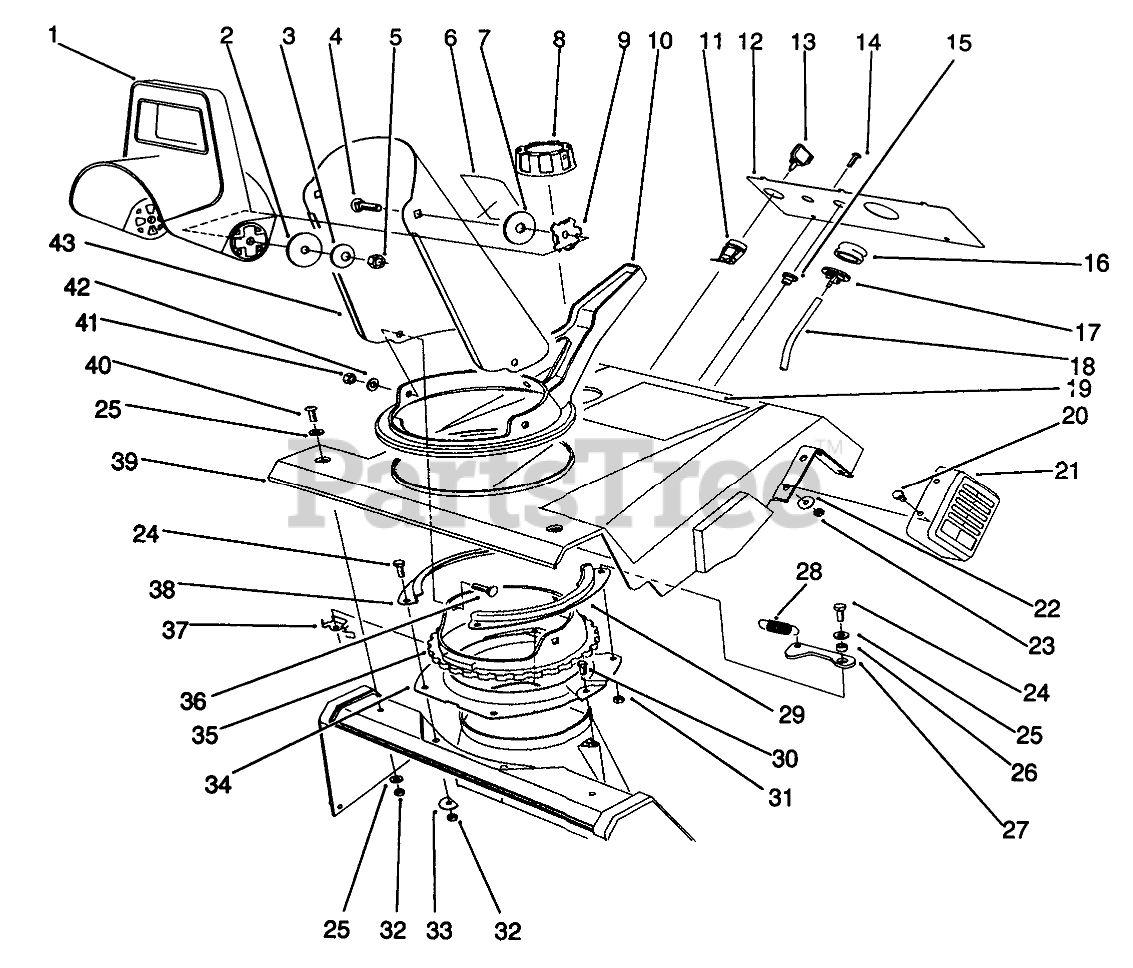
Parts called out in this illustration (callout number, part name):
1	CHUTE-DEFLECTOR
2	WASHER-FLAT
3	WASHER-BELLEVILLE
4	SCREW-CARR
5	NUT-LOCK, NI
6	DECAL-DANGER DISCH.
7	WASHER-RUBBER
8	GAS CAP ASSEMBLY
9	PLATE-FRICTION
10	CHUTE - HANDLE
11	SWITCH
12	CNTRL PANEL/SILK SCREEN
13	KEY-IGNITION
14	SCREW-SHWH, THREAD FORMING
15	GUIDE-ROPE, STARTER
16	BULB-PRIMER
17	BODY-PRIMER
18	HOSE-PRIMER
19	DECAL - CCR 1000E
20	SCREW-HWH
21	Guard-Muffler
22	WASHER-FLAT
23	NUT-LOCK, NI
24	SCREW-HH
25	WASHER-FLAT
26	SPACER-BLADE, ROTOR
27	DETENT
28	SPRING-EXTENSION
29	Retainer-Chute Ring
30	SCREW-PLASTITE
31	NUT-LOCK, NI
32	NUT-LOCK, NI
33	Washer
34	Ring-Chute Support
35	GEAR RING, CHUTE
36	SCREW-CARR
37	SPRING-EXTENSION
38	Retainer-Chute Ring
39	UPPER SHROUD
40	SCREW-PPH
41	NUT-KEPS
42	WASHER-FLAT
43	Discharge Chute Assembly (Incl. Ref. #6)
